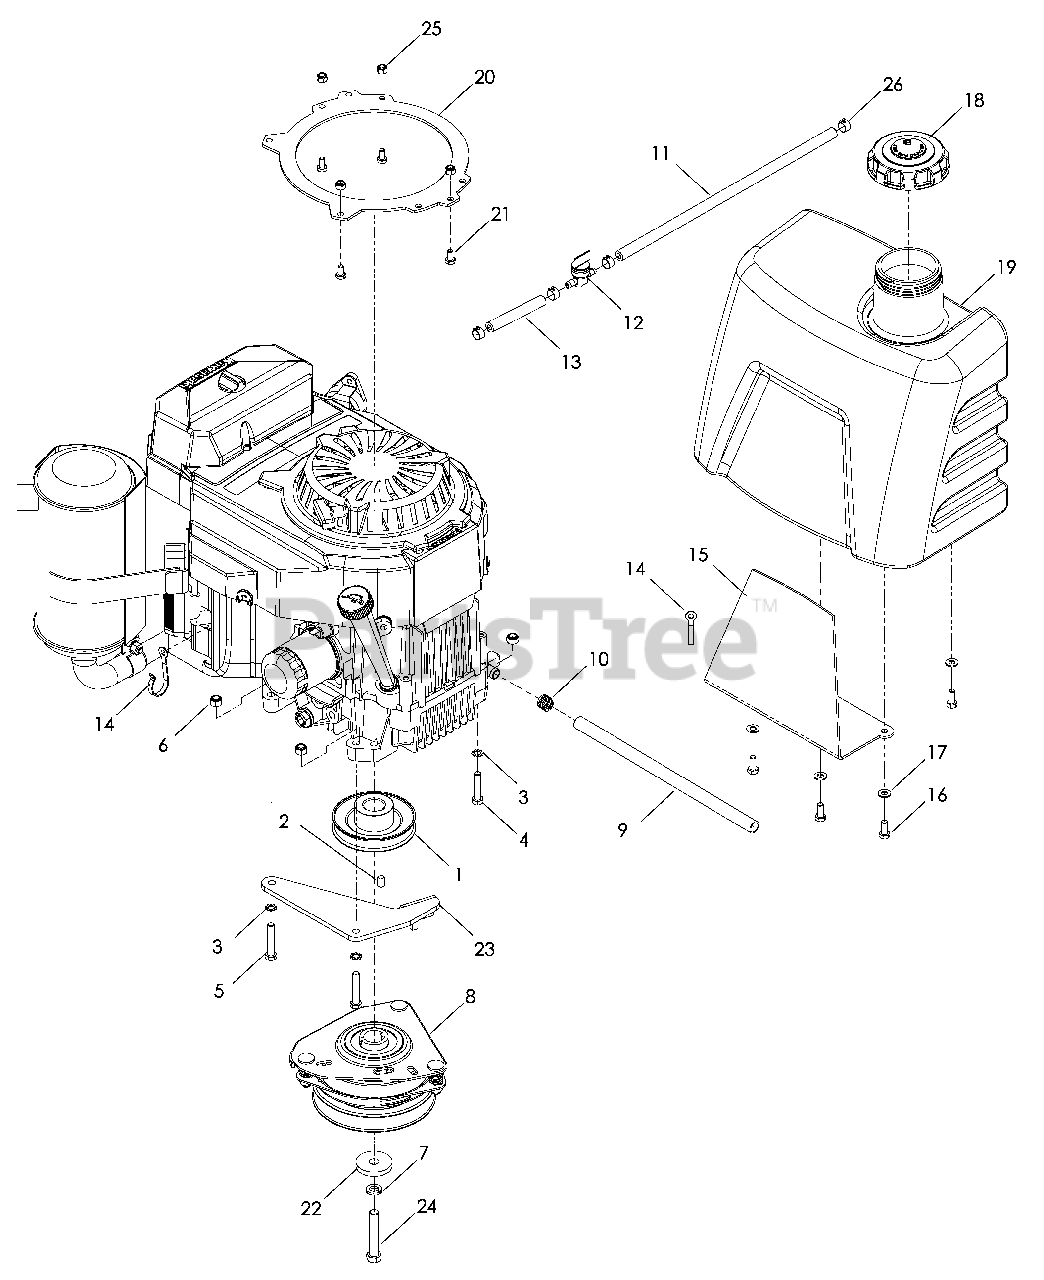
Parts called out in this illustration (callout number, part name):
2	KEY ¼" SQ x ½"
3	LOCK WASHER 5/16 STAR
4	HCS 5/16-18 x 1½
5	HCS 5/16-18 x 1¾
6	NUT 5/16-18 HEX NYLOC
7	LOCKWASHER 7/16 SLOT
8	CLUTCH 90 FT/LB
9	HOSE, OIL DRAIN
10	CLAMP, HOSE
11	FUEL LINE, 12"
12	FUEL VALVE
13	FUEL LINE, 2½"
16	HCS 5/16-18 x ¾
17	WASHER 5/16 SAE FLAT
18	CAP, FUEL TANK
19	TANK, FUEL
20	ADAPTER, RECOIL
21	HCS ¼-20 x ½
22	WASHER, HEAVY
23	CLUTCH STOP
24	HCS 7/16-20 x 2½
25	NUT ¼-20 HEX NYLOC
